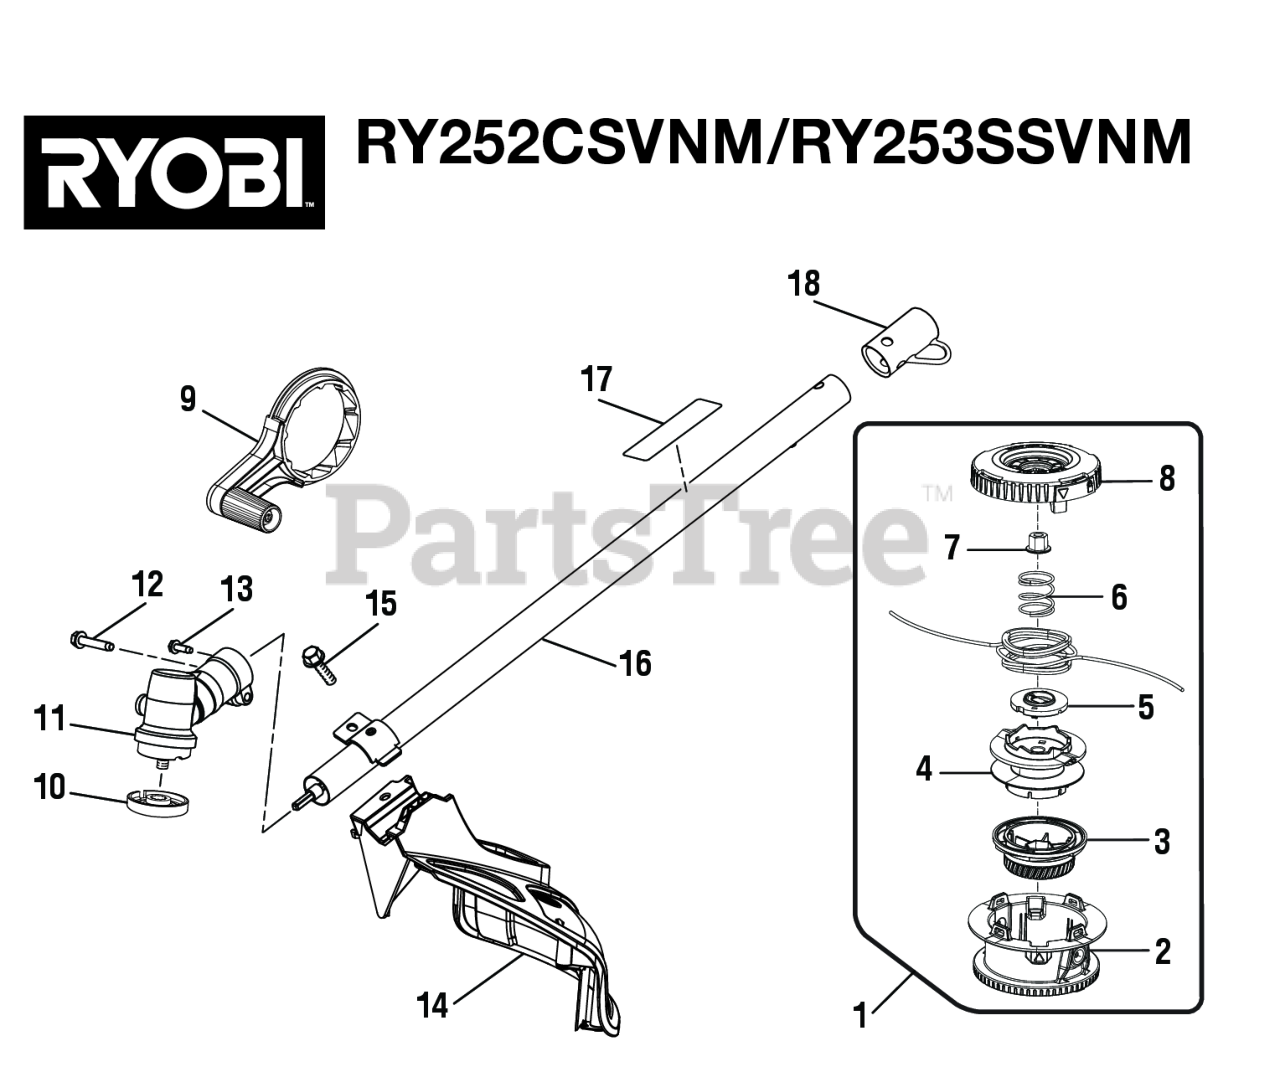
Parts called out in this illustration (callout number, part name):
1	Trimmer Head Assembly (.095) (Inc. Key Nos. 19-25)
2	Bump Head
3	Bump Knob (Green)
4	Spool Assembly
5	String Guide
6	Compression Spring
7	Hex Nut (M8, Left Hand Threads)
8	Locking Assembly
9	Crank Handle
10	FLANGED WASHER
11	Gear Case Assembly
12	Screw (1/4-20 x 1-1/4 in., Hex Washer Hd. S.T.)
13	Screw w/Washer (10-24 x 5/8 in., Hex Hd. T.F.)
14	Grass Deflector Assembly
15	SCREW (#1/4-20 X 1-1/4 in. HEX WASHER HD.)
16	Straight Shaft Assembly (Inc. Key Nos. 17-18)
17	Warning Icon Label
18	Hanger Cap
